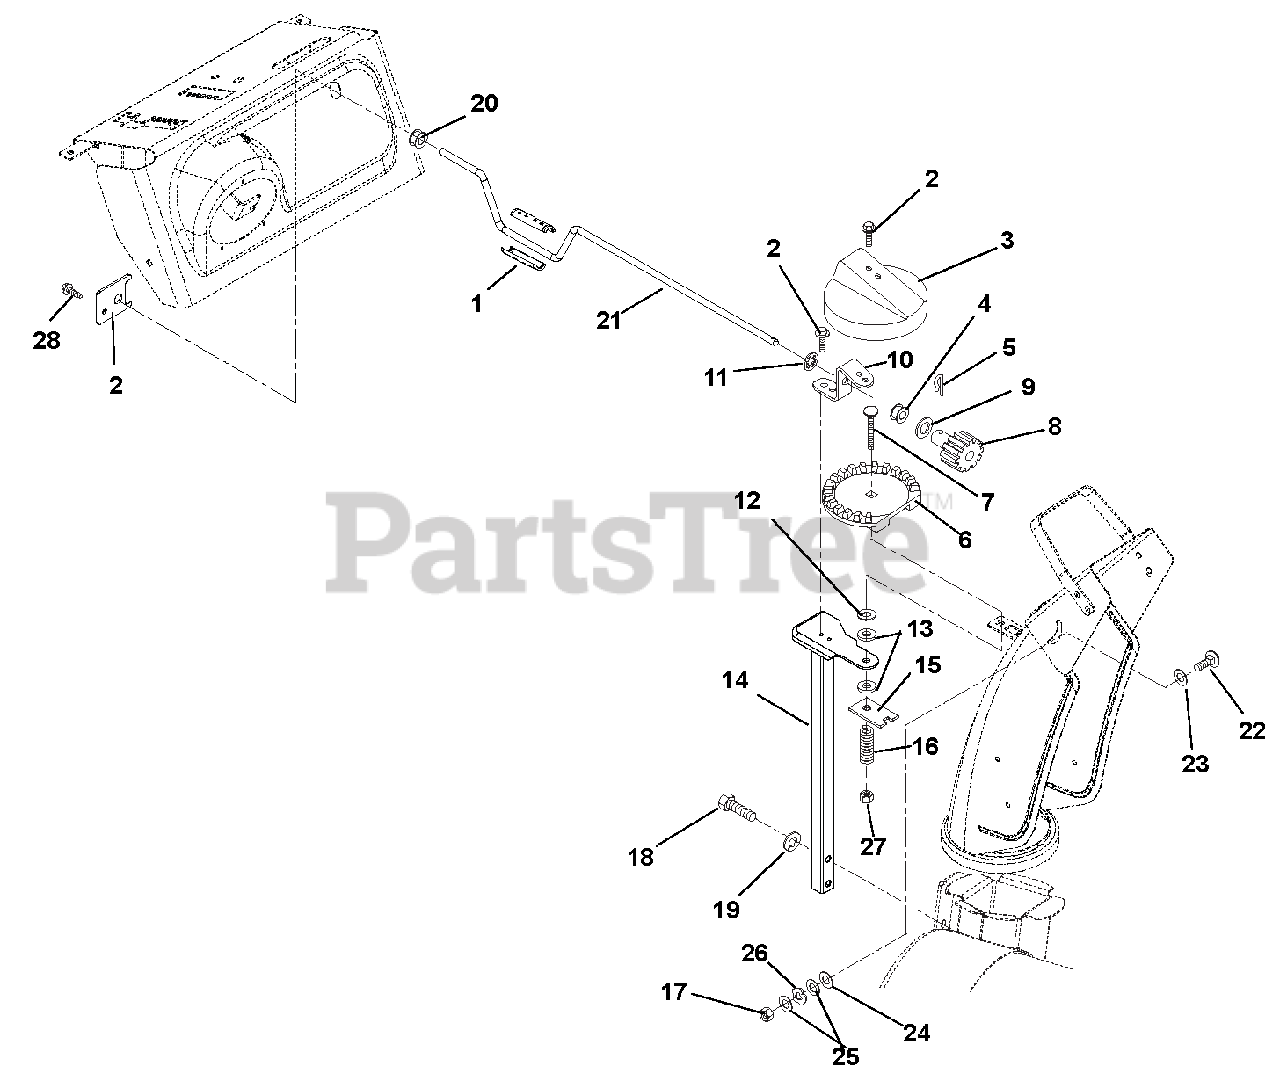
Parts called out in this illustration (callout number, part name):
1	KNOB, CRANK-SNAP
2	SCR-TAP .25-20X.50 HWH TR YWZ
3	GEAR COVER
4	BUSHING, POLYLINER-.63 SNAPIN
5	PIN, SPRING CLIP
6	CHUTE GEAR
7	@BLT-RDHDSQNK .38-16X2.50 G5YZ
8	PINION GEAR W/BRACKET
9	WSHR-THRST .625 X 1.0 X .03
10	BRACKET, PINION GEAR
11	PUSHNUT .625
12	WSHR-FL-STL .380X1.50X.062 YWZ
13	FRICTION WASHER
14	PEDESTAL, CHUTE - CRANK
15	PLATE, FRICTION
16	SG-COMP .187X.56X1.62
17	@NUT-LK-CTR .38-16 YWZC
18	@BLT-HEX .38-16X1.75 GR5 YWZC
19	@WSHR-LK .38X.094 REG YWZC
20	BUSHING, POLYLINER-.38 SNAPIN
21	ROD, CHUTE CRANK
22	@BLT-RHDSSQNK .38-16X.75 G5YZ
23	WSHR-FL-STL .52X.827X.062 YWZC
24	WSHR-FL-NY .375X.75X.060
25	@WSHR-FL-STL.406X.812X.065 YWZ
26	WAVE WASHER .390X.655X.110
27	@NUT-LK-TOP-FLG .38-16 YWZC
28	BRACKET, CHUTE CRANK
